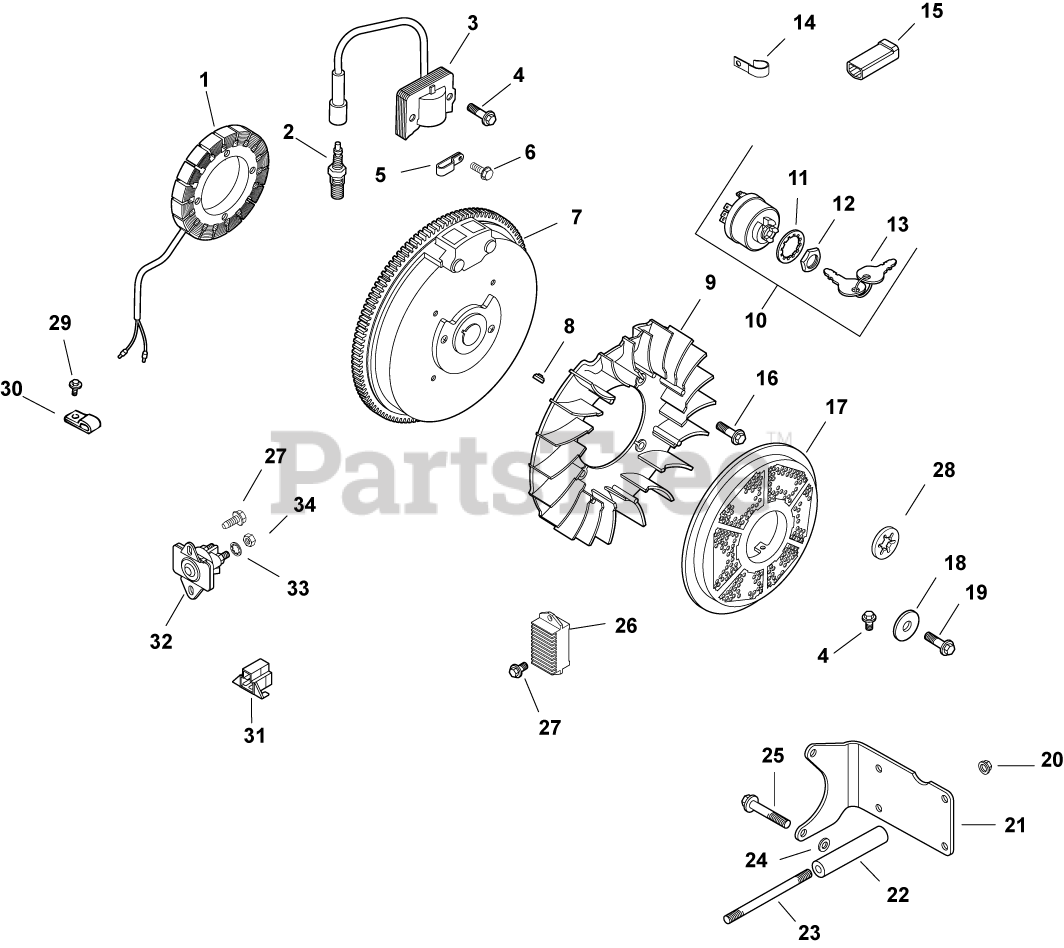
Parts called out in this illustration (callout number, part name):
1	KIT, 15 / 20 AMP STATOR
2	PLUG, SPARK (STD)
3	MODULE, IGNITION
4	SCREW, FLG THD FRM M5X.8X20-(#25086399S)
6	SCREW, FLG THD FRM M5X.8X10
7	FLYWHEEL ASSY PAINTED - USE 12 025 74-S
8	KEY, 3/16" X 5/8"
9	FAN - DISCONTINUED
10	SWITCH ASSY, KEY (KM)-USE 25 099 32-S
11	WASHER, INTERNAL TOOTH
12	NUT, KEY SWITCH
13	KEY, SET -USE 48 340 01-S
14	CLIP, CABLE
15	CONNECTOR (1 CONTACT)
16	BOLT, SHOULDER
18	WASHER, FLAT 13/32"
19	SCREW, FLG M10X1.5X45 - (#25086361S)
20	NUT, FLG M8X1.25
21	BRACKET, FUEL TANK
23	STUD, M8X1.25X133-USE 25 755 54-S
24	WASHER, FLAT 11/32"
25	SCREW, FLG M8X1.25X50
26	REGULATOR/RECTIFIER
27	SCREW,FLG THD FRM M6X1.0X16-(#25086397S)
29	SCREW, M5X0.8X25 - (#25086402S)
30	CLIP, TUBE & WIRING (KM)
31	CONNECTOR
32	SOLENOID - WATERPROOF (KM)-USE 25 435 08
33	WASHER, INT TOOTH LOCK 1/4"
34	NUT, JAM 1/4-20 GRADE 2
1251809-S	LEAD, STARTER SOLENOID - DISCONTINUED
2551829-S	LEAD, GROUND SOLENOID
